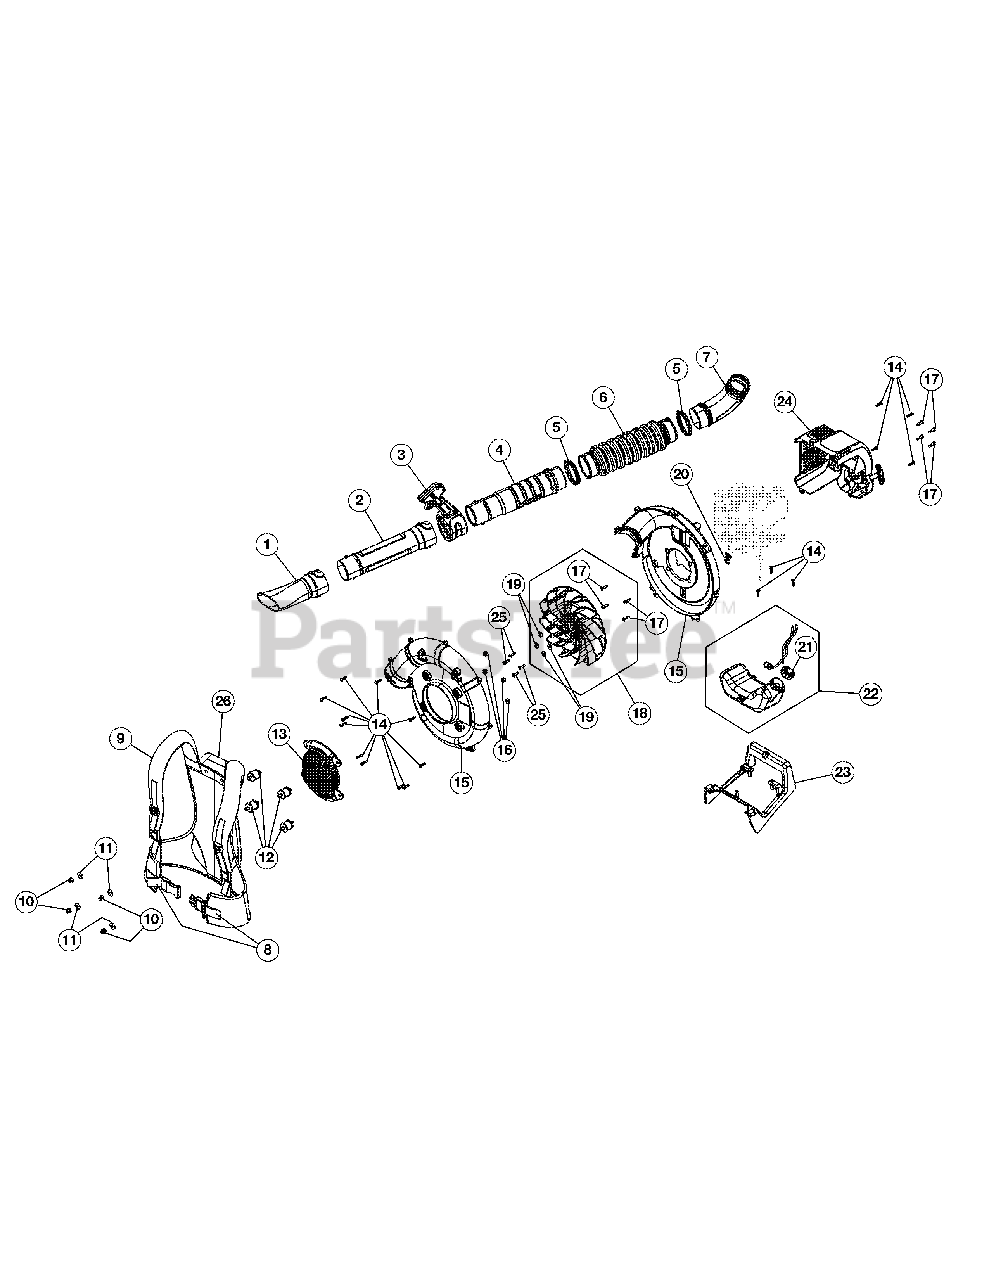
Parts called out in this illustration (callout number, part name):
1	Nozzle
2	Lower Blower Tube
3	Throttle Grip Assembly
4	Upper Blower Tube
6	Flex Tube
7	Elbow Tube
8	Hip Belt
9	Support System
10	Nut
11	Spacer
12	Isolator Mount
13	Intake Cover
15	Impeller Housing Assembly
16	Nut
17	Screw
18	Impeller (Incl. Ref No. 17 & 19)
20	Throttle Retaining Clip
21	Fuel Cap
22	Fuel Tank Assembly (Incl. Ref No. 21)
24	Engine Cover Assembly
